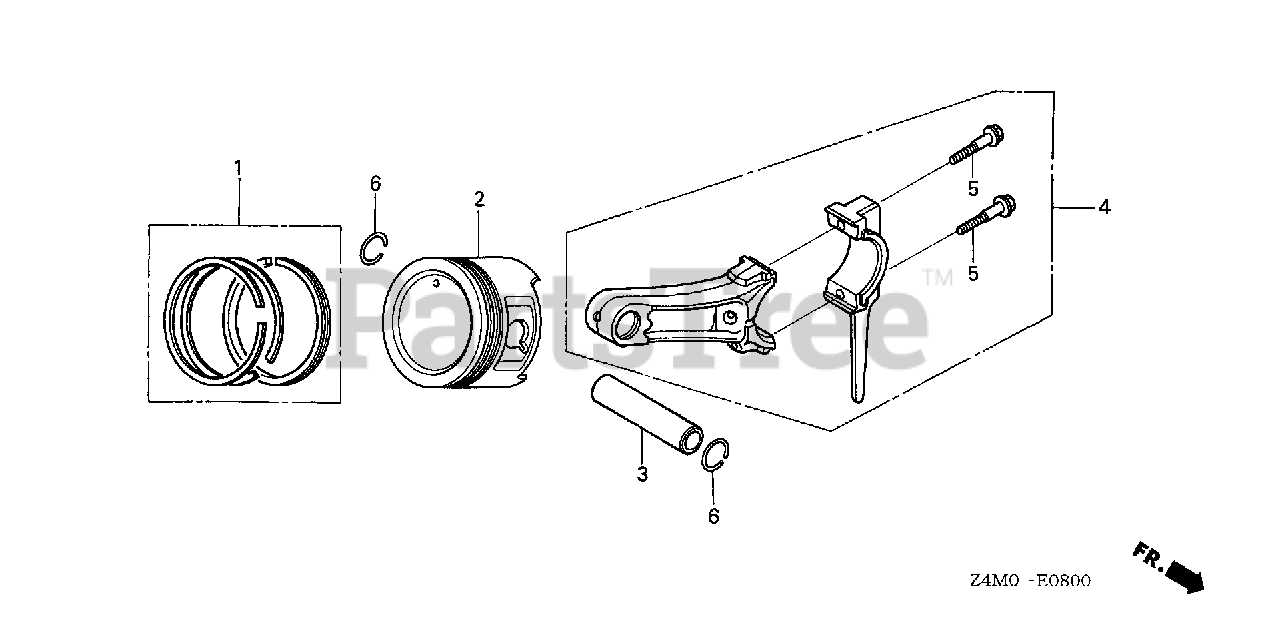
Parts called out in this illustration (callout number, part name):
1	RING SET, PISTON (STD)
1	RING SET, PISTON (STD) (TPR)
1	RING SET, PISTON (STD) (RIKEN)
1	RING SET, PISTON (OS 0.25) (Honda Code 7351372). (RIKEN)
1	RING SET, PISTON (0.25) Use from Engine SN 1314913.
1	RING SET, PISTON (0.25) (RIKEN)
1	RING SET, PISTON (OS 0.50) (Honda Code 7351380). (RIKEN)
1	RING SET, PISTON (0.50) (TPR)
1	RING SET, PISTON (0.50) (RIKEN)
1	RING SET, PISTON (0.75) (Honda Code 7351398). (RIKEN)
1	RING SET, PISTON (0.75) Use from Engine SN 1314913.
1	RING SET, PISTON (0.75) (RIKEN)
2	PISTON (STD)
2	PISTON (0.25) Use from Engine SN 1314913.
2	PISTON (OS 0.25)
2	PISTON (0.50) Use from Engine SN 1314913.
2	PISTON (OS 0.50)
2	PISTON (0.75) Use from Engine SN 1314913.
2	PISTON (0.75)
3	PIN, PISTON
4	ROD ASSY., CONNECTING (STD)
4	ROD ASSY., CONNECTING
5	BOLT, CONNECTING ROD
6	CLIP, PISTON PIN (18MM)
